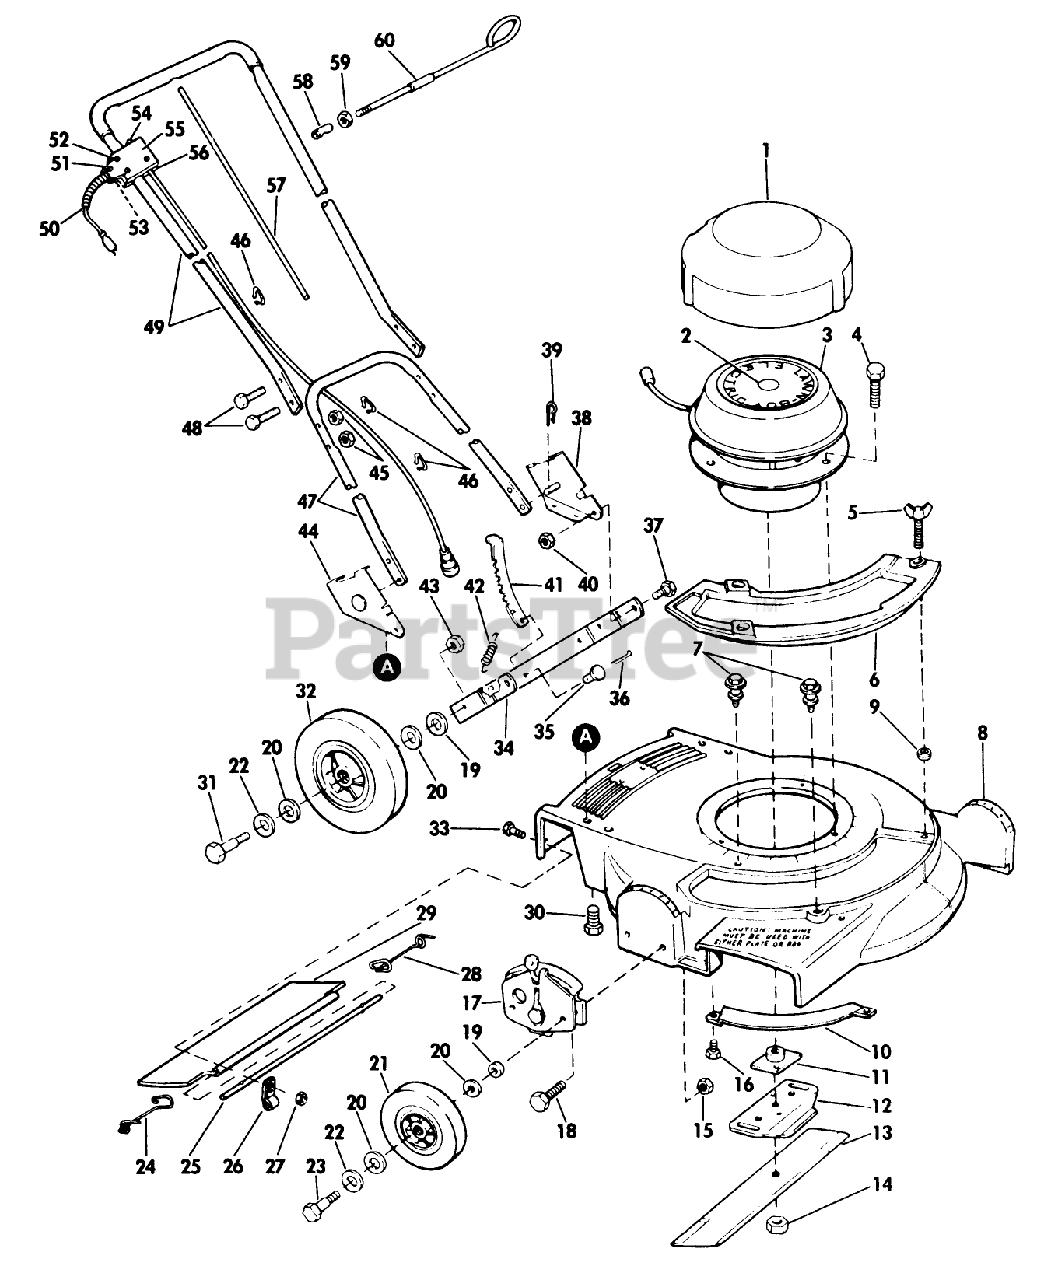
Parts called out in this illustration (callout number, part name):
4	SCREW
5	WING SCREW LAWRE
10	TOE BAR 19"
11	PLATE AND COLLAR ASM
14	NUT-BLADE
15	NUT
19	WASHER WROUGHT
20	WASHER
22	SPACER
23	BOLT WHEEL
24	SPRIG T/SHLD ASOC
25	ROD T/SHIELD ADV WIRE
26	CLAMP ROD KMC
28	SPRING;TRAILING SHIELD RH
31	BOLT
37	BOLT-SHOULDER
39	HAIR PIN
40	NUT
42	SPRING N.A.S
43	LOCKNUT
48	SCREW
51	Screw-Ground
53	NUT S
